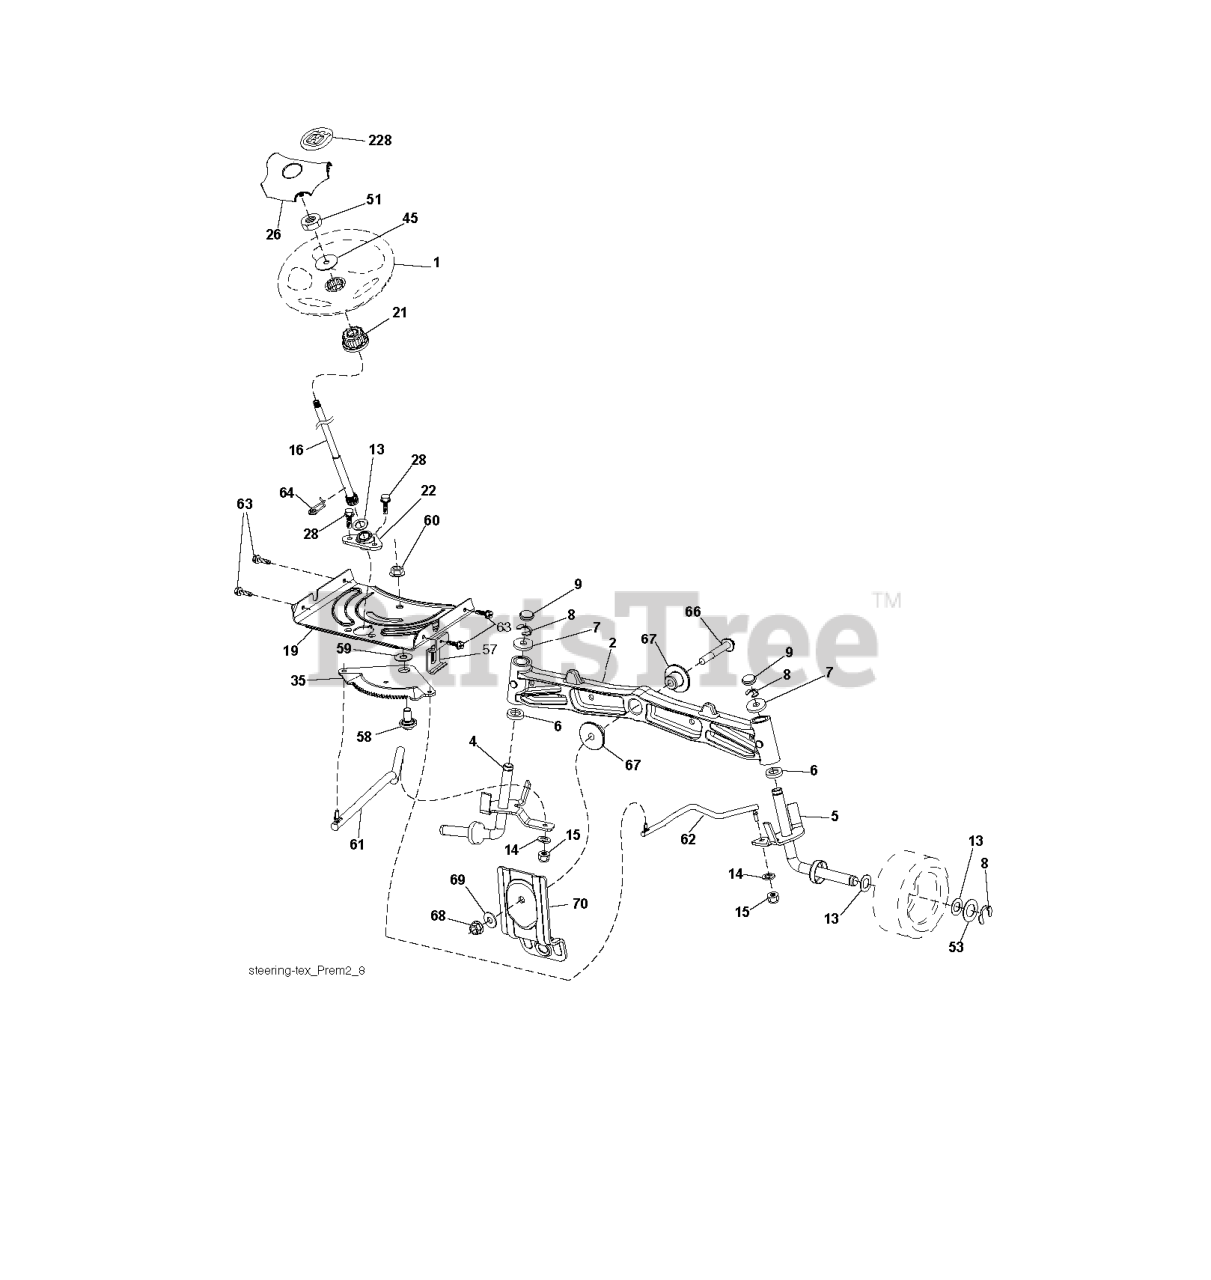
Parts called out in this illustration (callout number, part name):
1	RP WHEEL.STEER.HUSQ.PREM.OVMLD
2	AXLE.CAST.IRON
4	SPINDLE.WELDED.LH.15"TEX
5	SPINDLE.WELDED.RH.15"T
6	THRUST WASHER
9	CAP.SPINDLE.BLACK
14	WASHER, LOCK 3/8
15	NUT CROWNLOCK 3/8-24
16	SHAFT STEERING
19	PLATE.STEER.DDL.NLT/NG
20	BOOT, STEERING
21	ADAPTER, WHEEL STNG..
22	BUSHING.ASM.STEERING.A
26	RP INSERT.CAP.WHL.STRG.HUSQ.
28	SCREW, 3/8-16X3/4
33	WASHER.LOCK.HVY.HLCL.SPR.5/16
35	GEAR.SECTOR.PLATE.DDL.
45	WASHER.11/32
53	WASHER.HARDENED
57	BRACKET.UPSTOP.TEX
58	BOLT.SHOULDER.SECTOR.P
59	WASHER.THURST.SECTOR.S
60	NUT FLANGE LOCK 5/8-11
61	DRAGLINK.LH.BALLSTUD.D
62	DRAGLINK.RH.BALLSTUD.D
63	SCREW
64	RETAINER.CLIP.SPRING.S
66	BOLT HEX FGHD 7/16-14 X 3 SERR
67	BUSHING.PM.FRONT AXLE
68	NUT.LOCK.FLANGE.7/16
69	WASHER.1.5X.505X.118
70	BRKT.DECK.SUSPENSION.F
71	SHAFT EXTENSION STEERING
72	BOLT YT
228	DECAL.WHEEL.STRG.LGN.H
